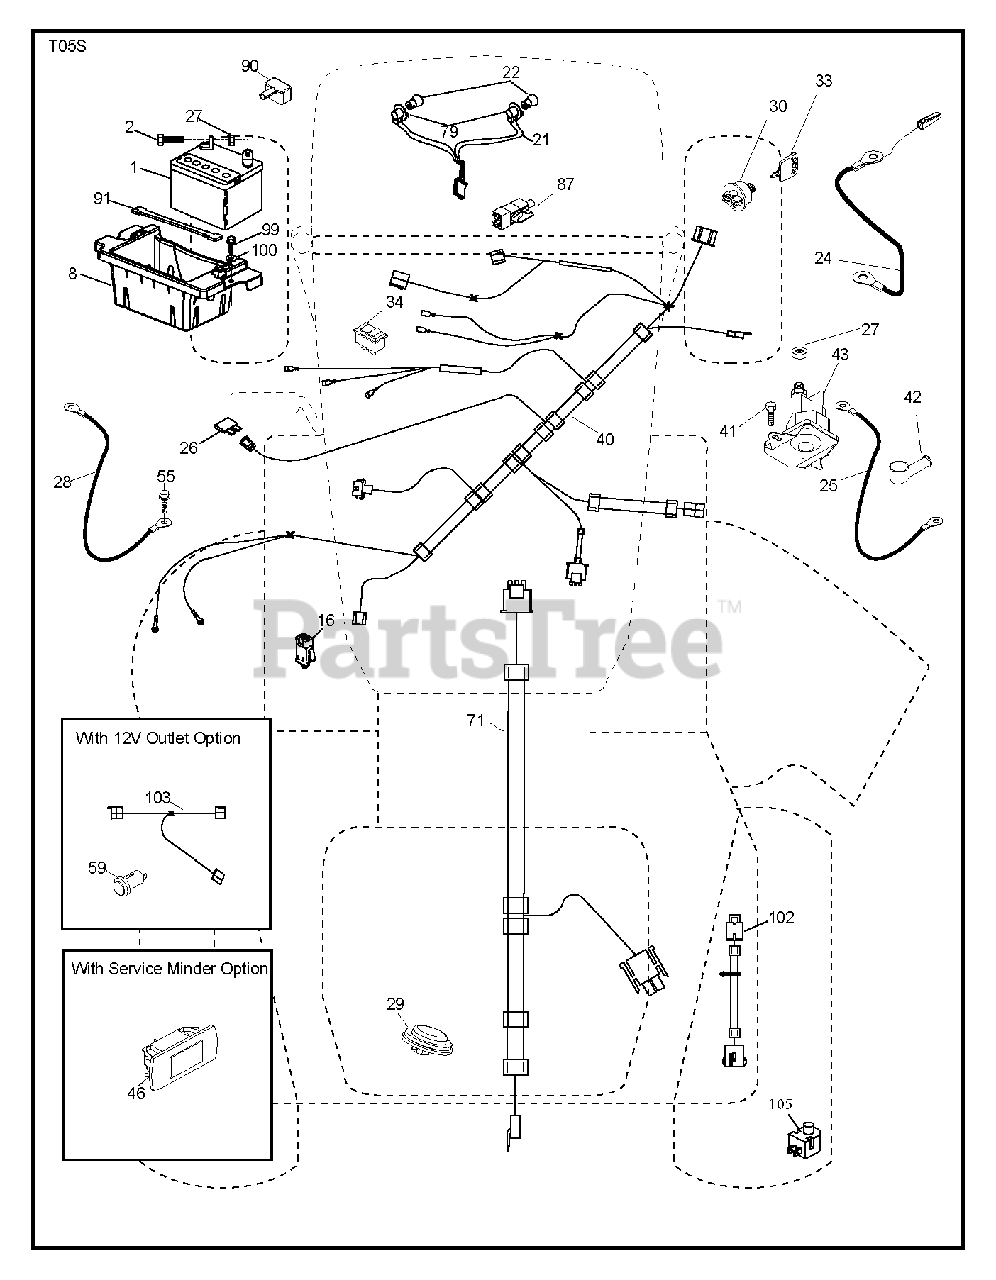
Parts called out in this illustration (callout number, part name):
1	REPL BY 532 12 38-99
2	BOLT.HEX.1/4.X.3/4.DICHROMATE
8	BOX.BATTERY.MOUNT.FRONT.LT
16	SWITCH INTERLOOK PUSH-IN
21	HARNESS ASSY LIGHT
22	LIGHTBULB
24	CABLE.BATT.POS.WIRE.TG.DA SOL
25	CABLE.STARTER.6GA.BL/RED.14.
26	FUSE 20AMP
27	NUT
28	CABLE GROUND 6 GA 21" 90T BLK
29	SWITCH.SEAT.DELTA.OPC.
30	SWITCH.IGN.DELTA.W.LGH.ROS
33	KEY.CHAIN.BLISTER.PACK.GEN.USA
34	SWITCH LT
40	HARNESS IGN. DASH
41	SCREW
42	TERMINAL COVER
43	SOLENOID.W/BRASS.PLUNGER
46	GUAGE.SRVCMNDR.HRMTR.
55	SCREW 5/16"
71	HARNESS-CHASSIS SUB
79	BULB HOLDER ASM.
87	SWITCH.INTRLCK.CLUTCH.
90	COVER.TERMINAL.BATTERY
91	STRAP.BATTERY.MOUNT.FRONT
99	SCREW HEXWSHR 1/4-20X3/4
102	HARNESS PIGTAIL PCH TEX ROS
105	REVERSE SWITCH
